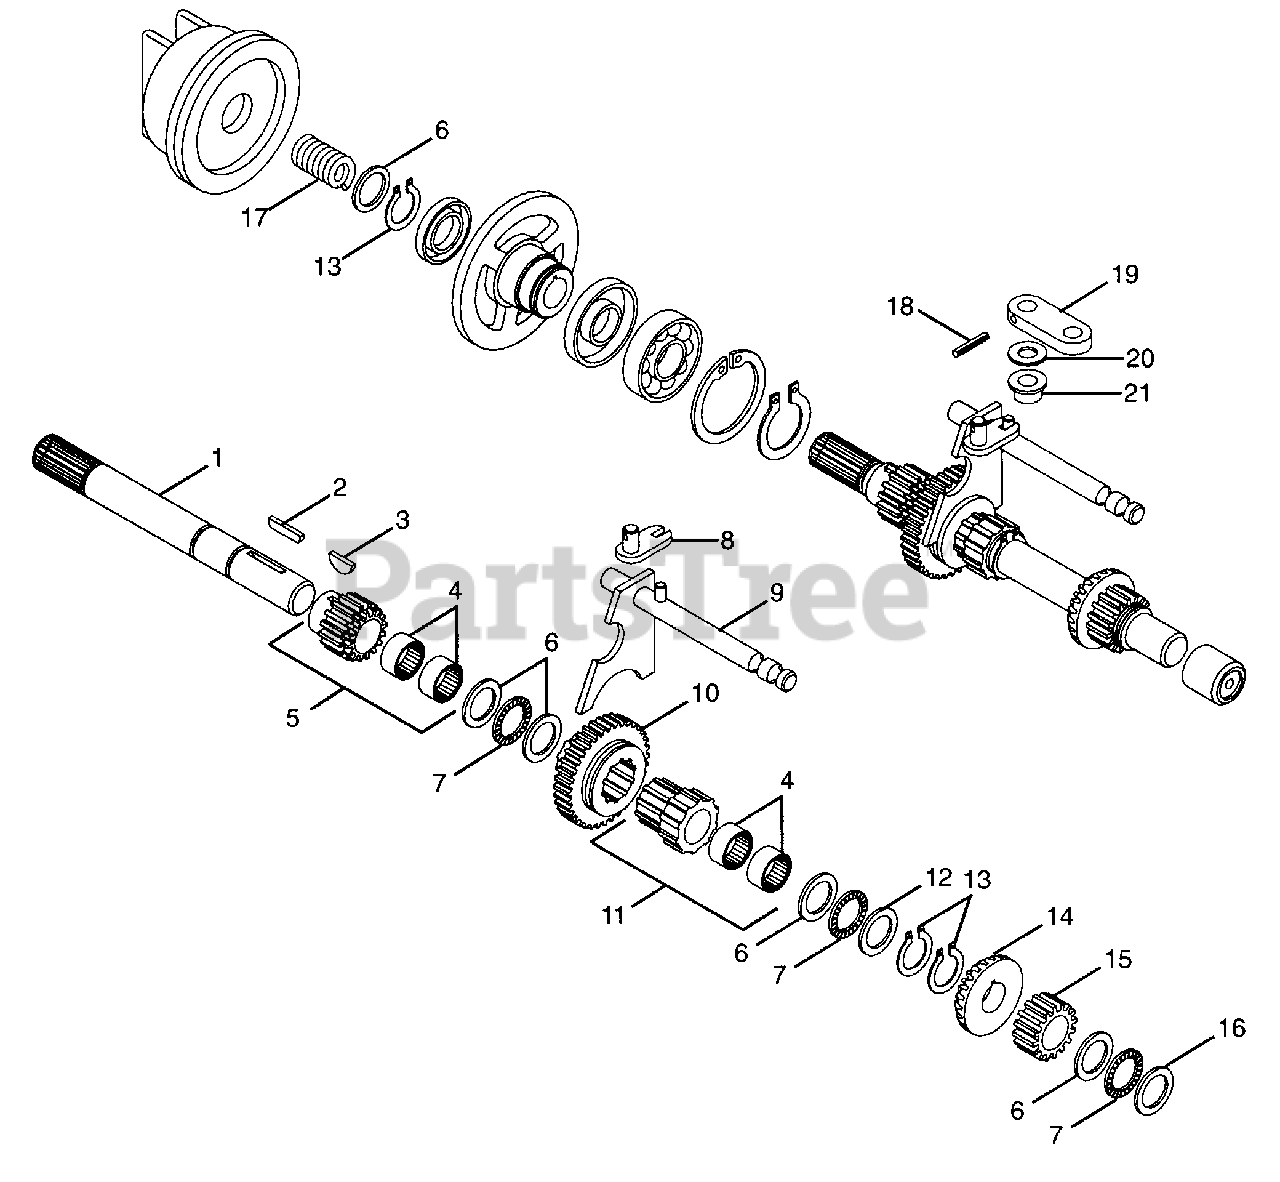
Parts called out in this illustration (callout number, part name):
1	Shaft-Forward Clutch
2	Key-Woodruff .19 x 1.25
3	Key-Woodruff .19 x .63
4	Bearing-Roller .75 x 1.0 x .50
5	Gear and Bearing Assembly
6	Bearing-N-Thrust .752 x 1.24 x .031
7	Bearing-N-Thrust .754 x 1.24 x .078
8	Weldment-Shifter
9	Weldment-Shift Rail
10	Gear-Spur 25 P 10 DP 36 T
11	Gear and Bearing Assembly
12	Washer-Thrust .752 x 1.240 x .062
13	Ring-Retaining-Internal .750 x .042
14	Gear-Bevel
15	Gear 10 DP 16 Teeth x .750
16	Bearing-N-Thrust .752 x 1.24 x .093
17	Spring-Compression .085 x .80 x 1.00
18	Pin-Roll .187 x 1.000
19	Arm-Shifter
20	Washer-Felt .437 x 1.00 x .031
21	Bushing-Flange .626 x .500 x 1.0
